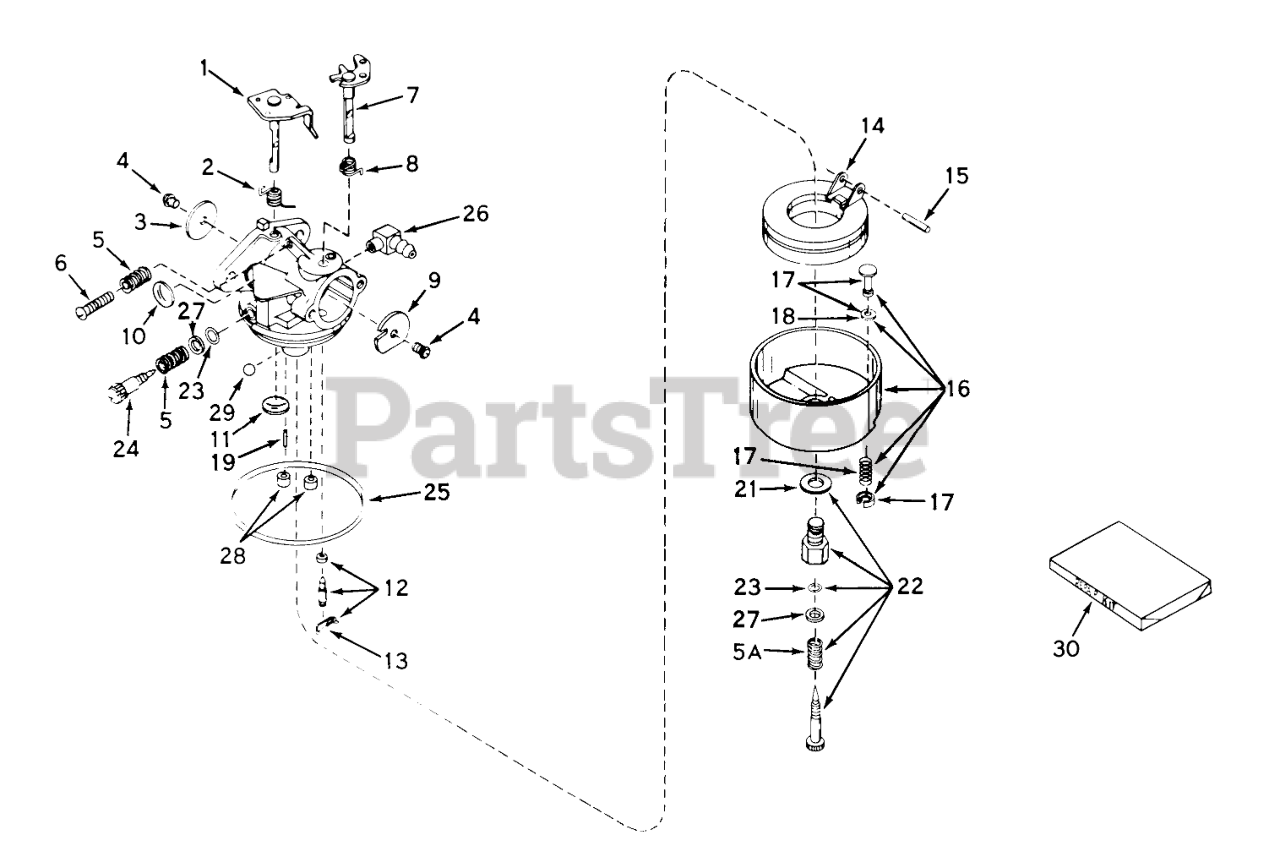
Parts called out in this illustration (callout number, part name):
1	Shaft & Lever Assy.
2	Spring, Throtte Return
3	Shutter-Throttle
4	Screw-Shutter
5	Spring-Tension
6	Screw-Throttle Crack Screw / Idle Speed
7	Shaft& Lever Assy., Choke
8	Spring, Choke return
9	Shutter, Choke
10	Plug-Welch, Idle Mixture Well
11	Plug-Welch, Atmospheric Vent
12	Inlet Needle, Seat & Clip Assy. (Incl. No. 13)
13	Clip-Spring
14	Float,Carburetor
15	Shaft-Float
16	Bowl & Drain Assy., Float (Incl. No. 17)
17	Plunger Assy., Drain (Incl. No. 18)
18	Gasket-Plunger, Drain
21	Washer-Bowl Nut
22	Adjustment Screw Assy., Main (Incl. Nos. 5A, 21, 23 & 27)
23	"O"Ring
24	Screw, Idle Adj.
25	O Ring-Bowl, Float
26	Fitting Fuel Inlet
28	Plug, Cup
29	BalI, Steel
30	Repair Kit
